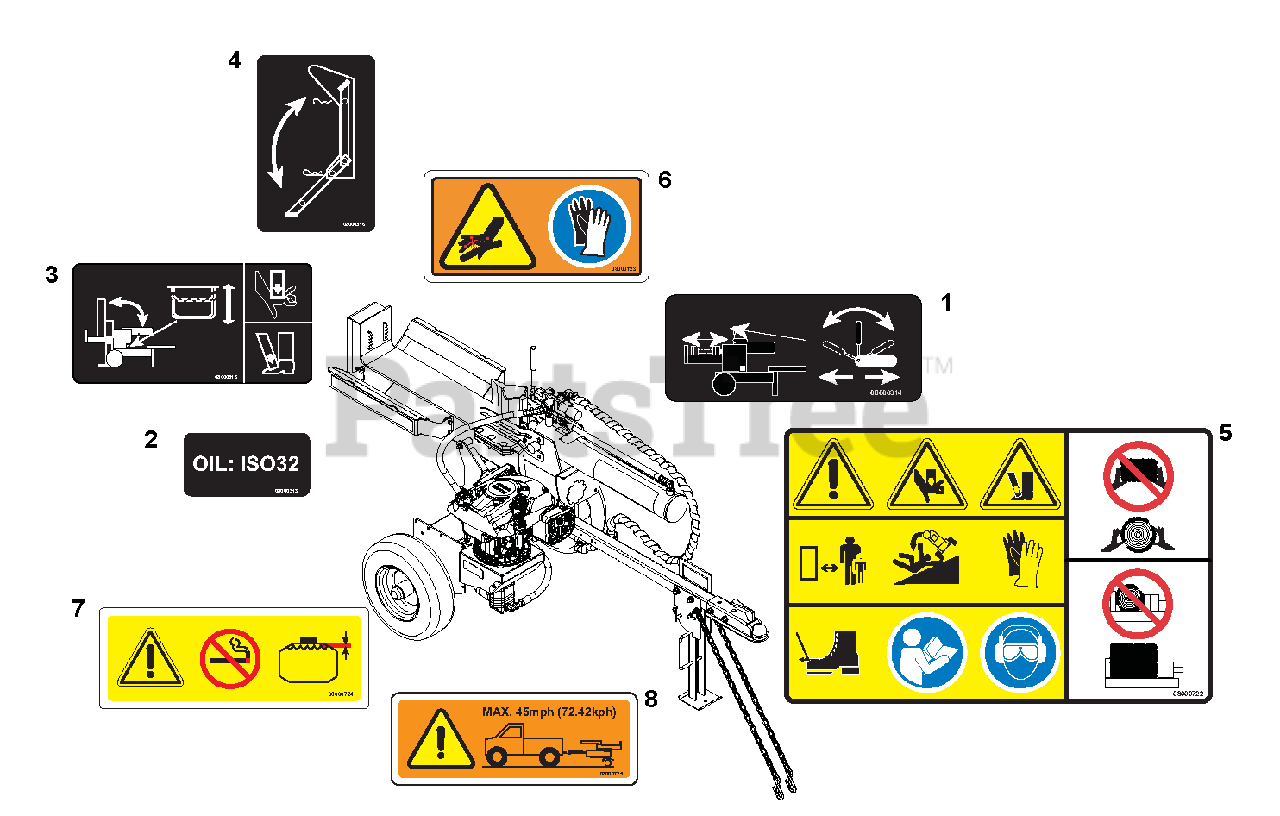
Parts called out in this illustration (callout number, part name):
1	DECAL, LOG SPLITTER-HYD OIL
2	DECAL, LOG SPLITTER-RAM OP
3	DECAL, LOG SPLITTER-TILT OP
4	DECAL, LOG SPLITTER-REAR STAND
5	DECAL,DANGER LOG SPLITTER
6	DECAL,HYD WARNING
7	DECAL,FUEL WARNING
8	DECAL,TOWING
